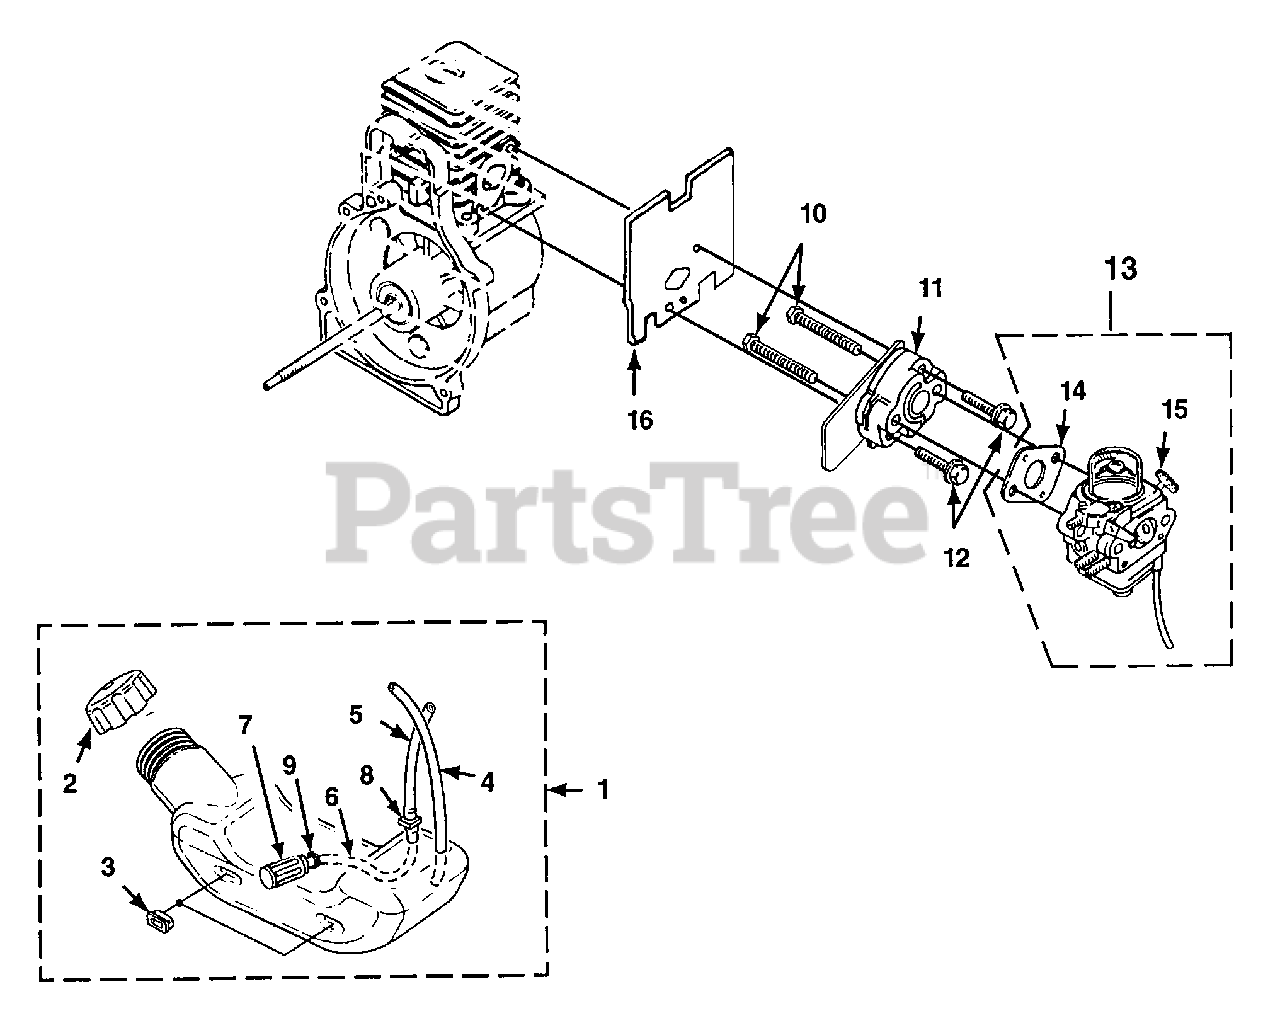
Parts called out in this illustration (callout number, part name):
1	FUEL TANK KIT
2	FUEL CAP (1 5/8" Opening)
3	BUMPER-Rubber
4	TUBING-Rubber
5	TUBING-Rubber
6	TUBING-Rubber
7	FUEL FILTER
8	FITTING
9	CLAMP
10	SCREW-Machine (10-24 x 2 1/4")
11	HEAT DAM
12	SCREW, SEMS (10-24 x 1")
13	CARBURETOR KIT
14	GASKET-Carburetor
15	LEVER-Choke (Walbro)
16	GASKET-Heat Dam
